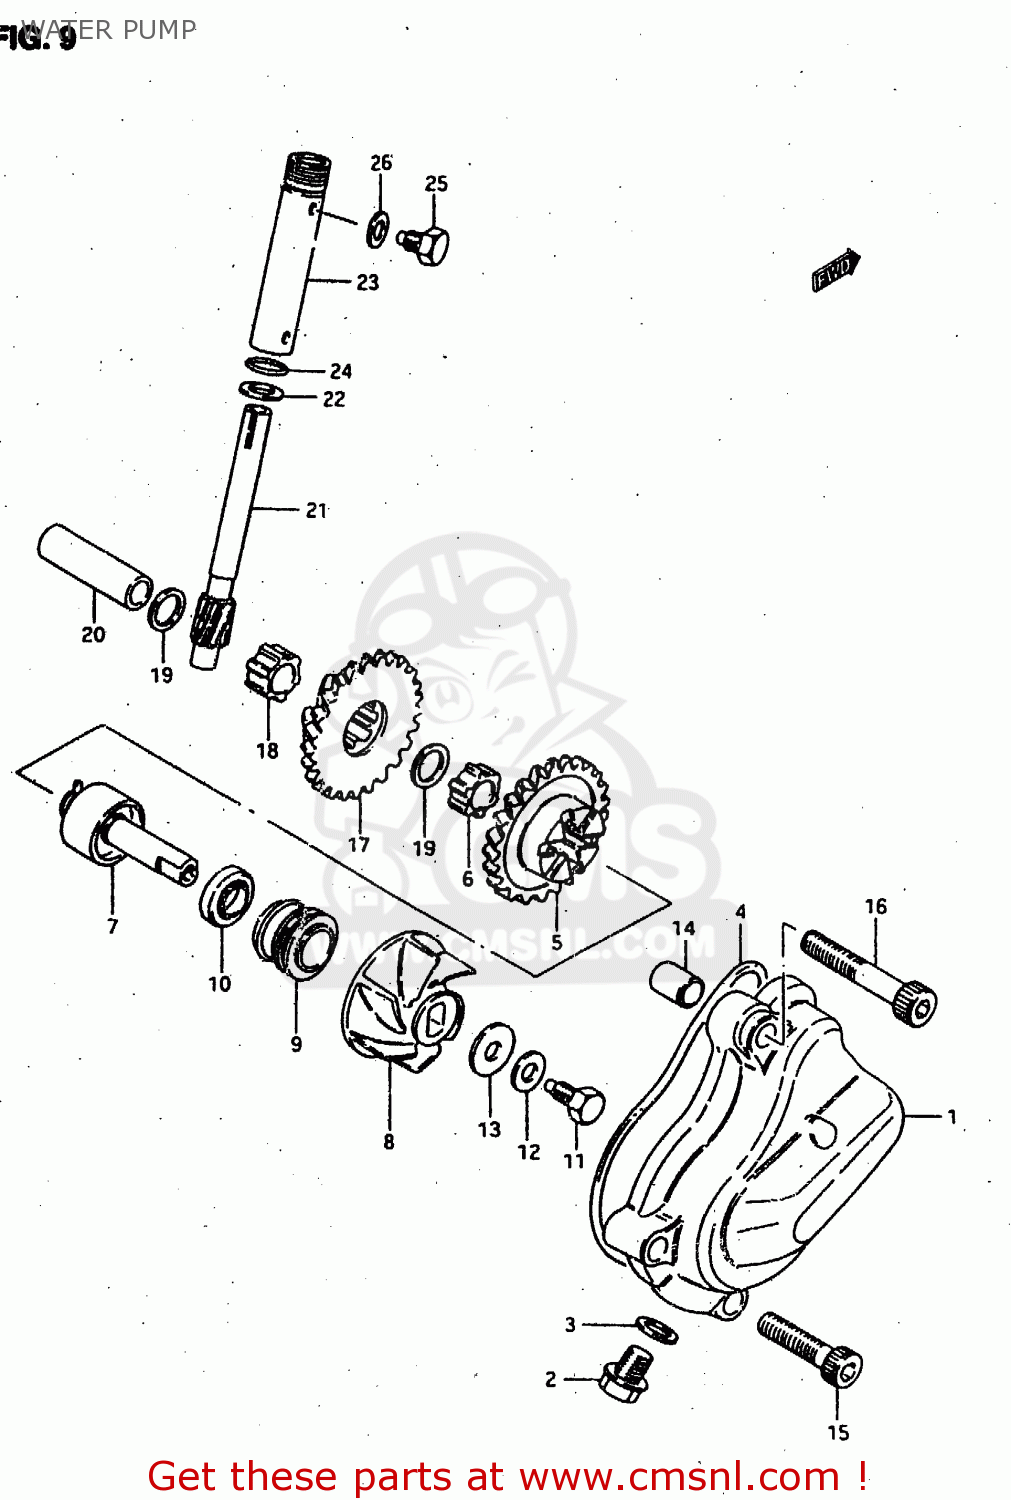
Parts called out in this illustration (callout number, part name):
1	CASE,WATER PUMP
2	BOLT,DRAIN
3	GASKET 8.2X14X1 (NAS)
4	O RING,WATER PUMP CASE
5	GEAR,WATER PUMP DRIVE
6	BUSH
7	SHAFT,WATER PUMP
8	IMPELLER,WATER PUMP
9	SEAL,MECHANICAL
10	SEAL,OIL(10X20X5)
11	BOLT(6X13)
12	WASHER
13	GASKET(6X15X2.2) (NAS)
14	PIN
15	BOLT,CL.COVER
16	BOLT
17	GEAR,TACHOMETER DRIVE
18	BUSH,TACHOMETER DRIVE GEAR
19	SHIM
20	SHAFT,TACHOMETER DRIVEN GEAR
21	GEAR,TACHOMETER DRIVEN(NT:10)
22	WASHER(8X13.7X1)
23	SLEEVE,TACHOMETER DRIVE GEAR
24	O RING(D:1.3,ID:9.6)
25	BOLT
26	GASKET(6.2X11X1).2 (NAS)
